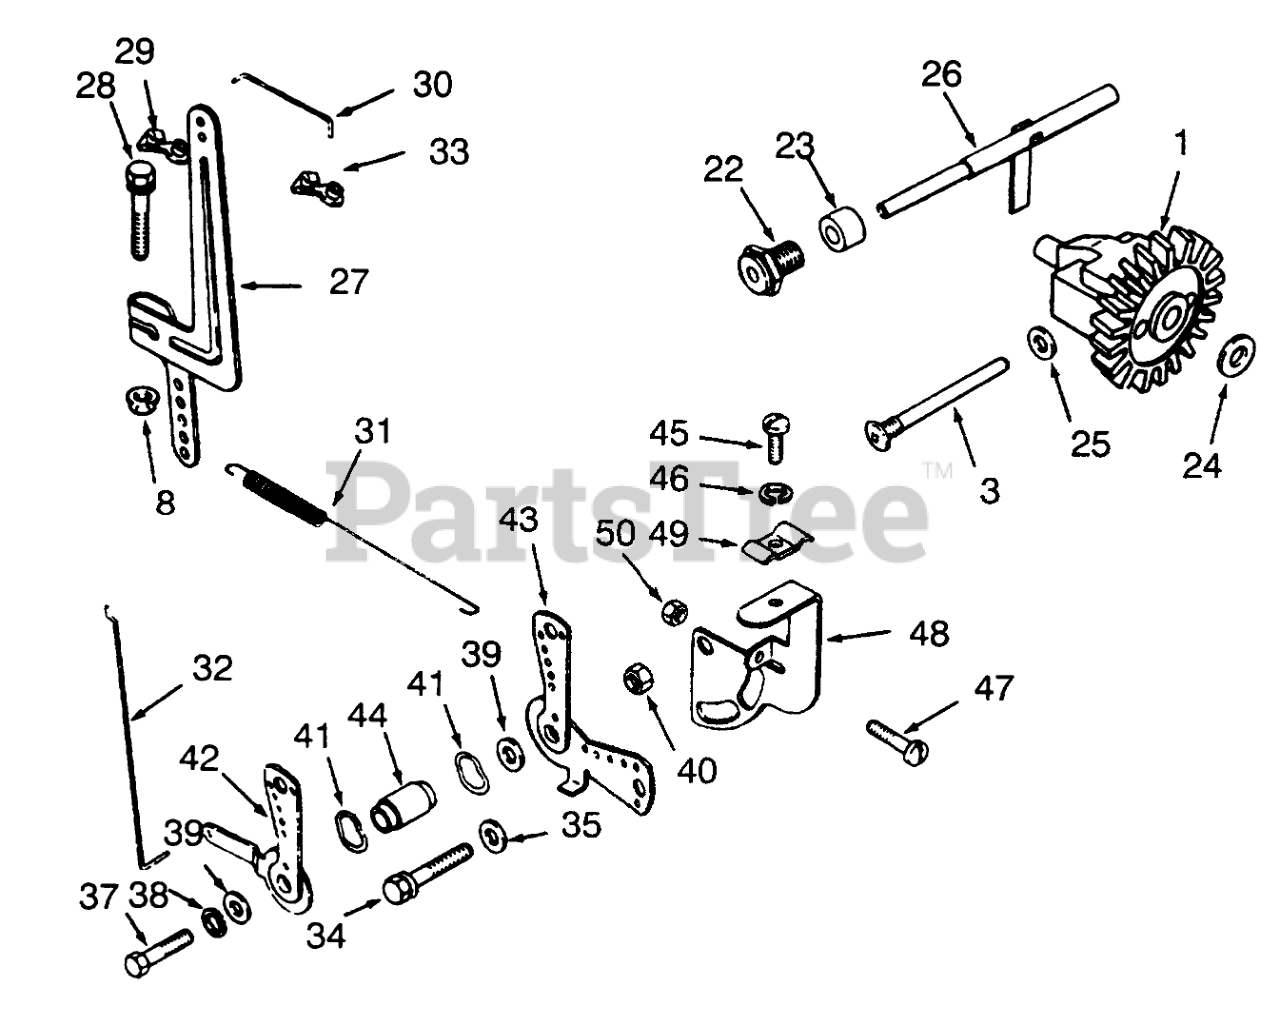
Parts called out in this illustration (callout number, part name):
1	Kit-Governor Gear (Incl. Ref.# 24)
3	Govenor Stop Pin
8	Palnut
22	Bushing
23	Spacer
24	Washer
25	Washer
26	Kit-Governor Cross Shaft
27	Governor Lever
28	Screw
29	Bushing
30	Carburetor Linkage
31	Spring (Governor to Cab.)
32	Choke Linkage (Carb. to Choke Shaft)
33	Bushing
34	Screw
35	Washer
37	Screw
38	Washer-Lock
39	Washer
41	Washer
42	Choke Control Lever
43	Lever-Throttle Control
44	Space
45	Screw
46	Washer
47	Screw
48	Bracket-Clutch Control
49	Clamp
